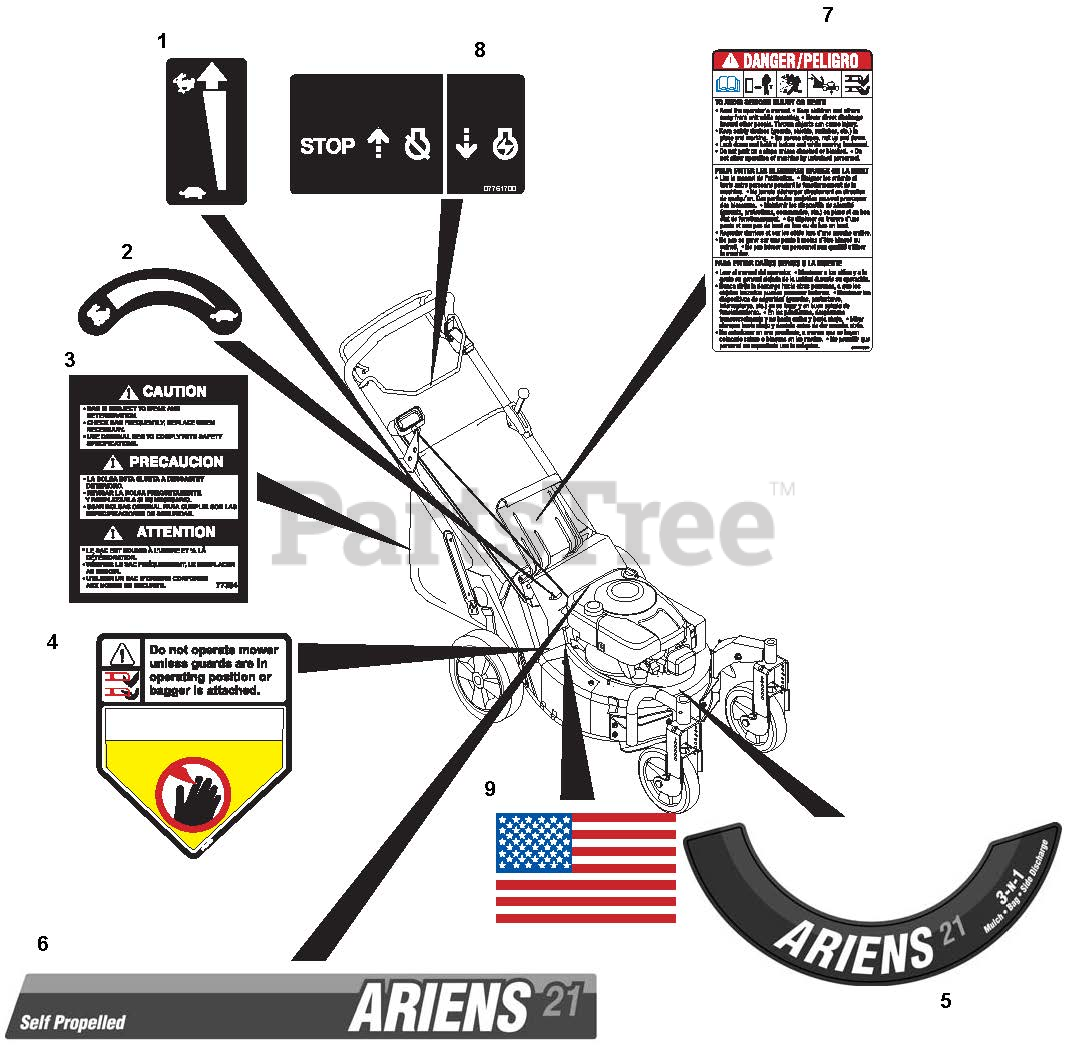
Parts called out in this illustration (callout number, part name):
1	DECAL-SPEED CONTROL
2	DECAL, TURTLE & RABBIT
3	LABEL - BAGGER 21"
4	DECAL, CPSC DANGER
5	DECAL, ARIENS DECK
6	DECAL, DRIVE COVER SP
7	DECAL, BILINGUAL DANGER
8	DECAL - ENGINE CONTROL
9	DECAL, AMERICAN FLAG
